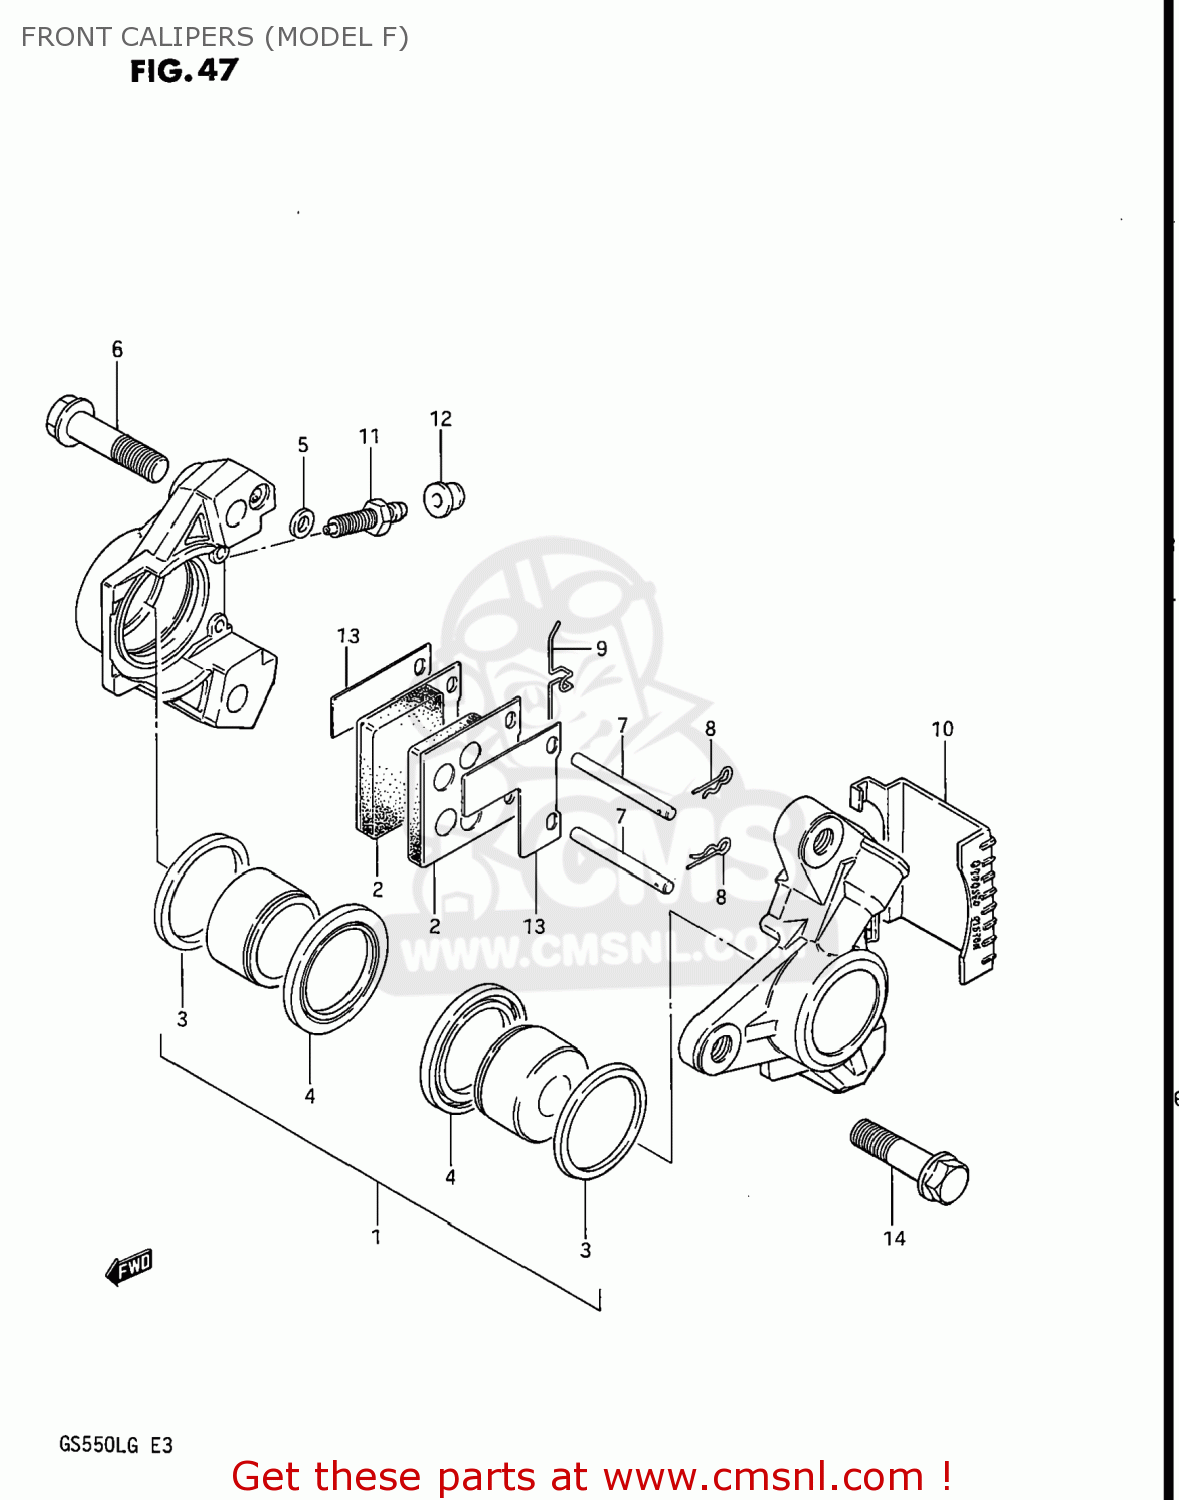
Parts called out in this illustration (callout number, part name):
1	PISTON SET
2	PAD (MCA)
3	SEAL,PISTON
4	BOOT
5	SEAL,JOINT
6	BOLT,HOUSING
7	PIN,PAD
8	CLIP,PAD PIN
9	SPRING
10	COVER,CALIPER
11	BLEEDER
12	CAP,BREATHER
13	SHIM
14	BOLT
